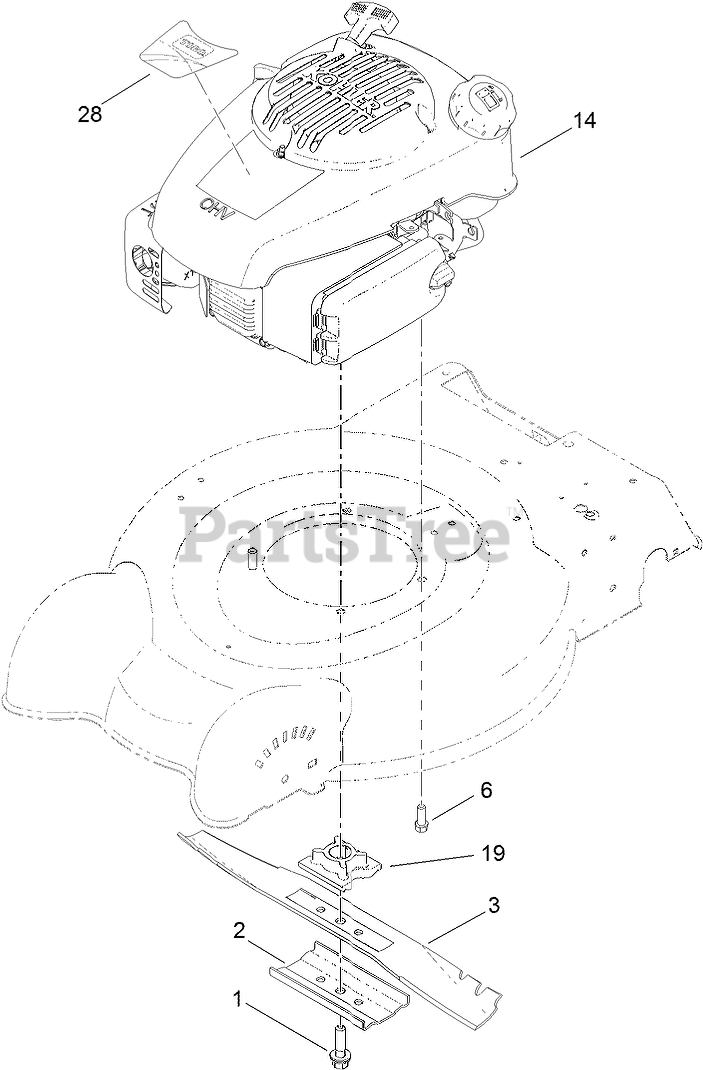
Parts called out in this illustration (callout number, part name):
1	BOLT-BLADE
2	SUPPORT-BLADE
3	BLADE-20 INCH
6	SCREW-TAPTITE
19	RETAINER-BLADE
28	DECAL-ENGINE
